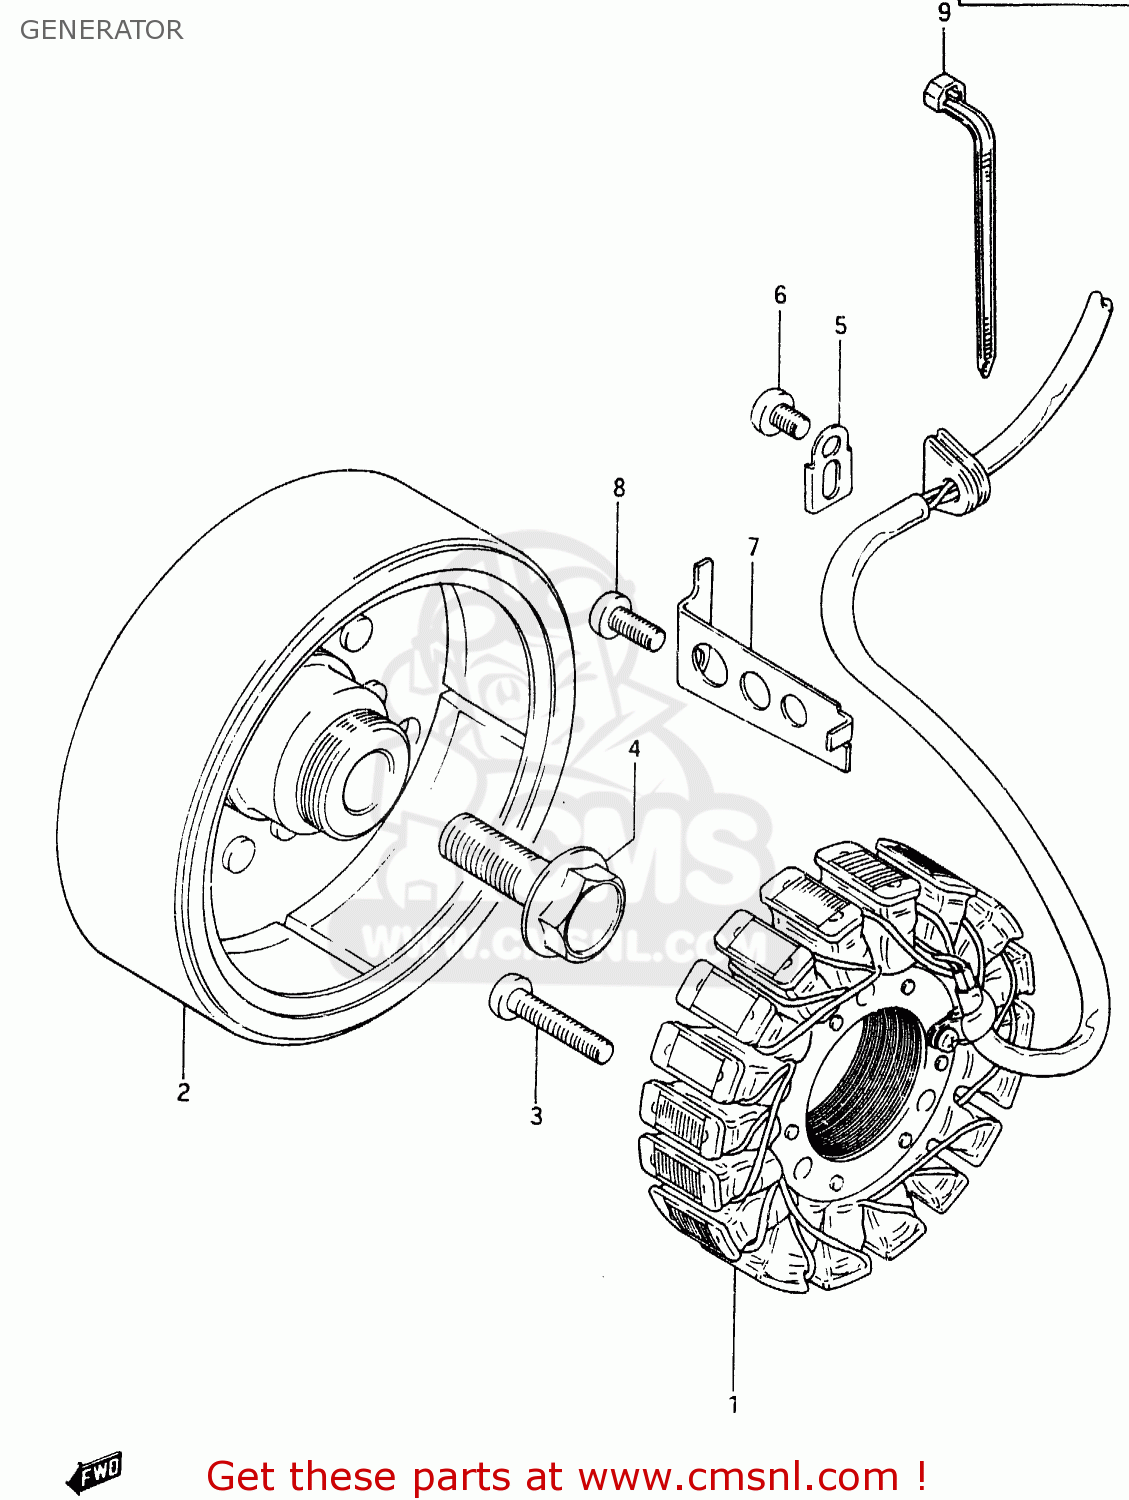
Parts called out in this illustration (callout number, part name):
1	STARTER ASSY
2	ROTOR ASSEMBLY
3	SCREW 6X30
4	BOLT(14X43)
5	CLAMP,GENERATOR LEAD WIRE
6	SCREW
7	CLAMP,GENERATOR LEAD WIRE
8	SCREW
9	CLAMP(L:95)
